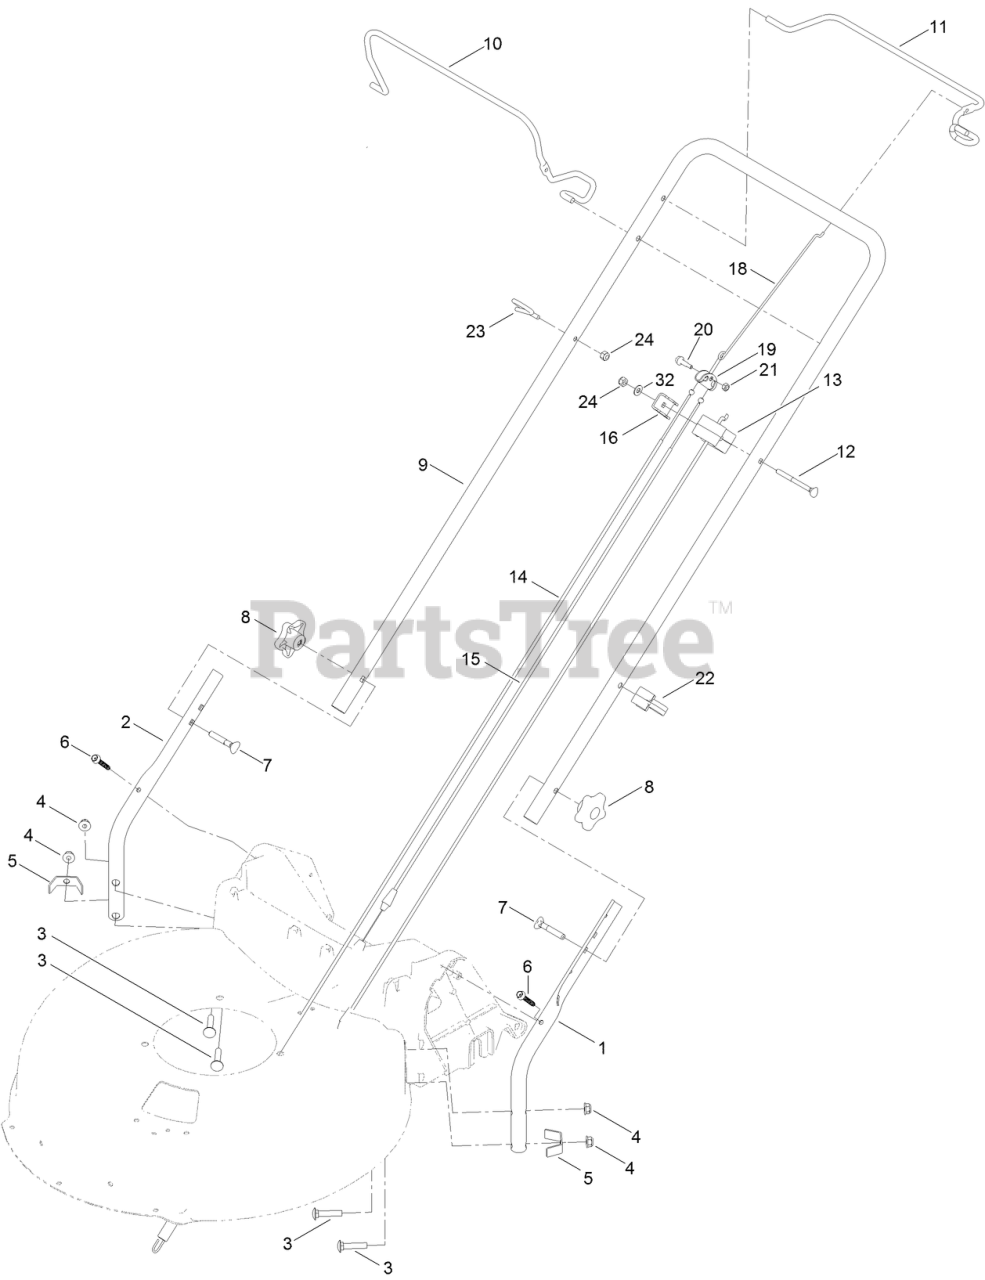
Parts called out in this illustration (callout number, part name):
1	HANDLE-LOWER, LH
2	HANDLE-LOWER, RH
3	BOLT-CARR
4	NUT-FLANGE, NI
5	BRACKET-CHUTE
6	SCREW-FLANGE, SERRATED
7	SCREW-HANDLE
8	KNOB-HANDLE
9	HANDLE-UPPER
11	BAIL-TRACTION
12	SCREW-HANDLE
13	CABLE-BRAKE
14	CABLE-TRACTION, FRONT
15	CABLE-TRACTION, REAR
16	CLAMP-CABLE
18	LINKAGE, EQUALIZER
19	YOKE-CABLE
20	SCREW-SHOULDER
21	NUT-LOCK, NI
22	GUIDE-CABLE
23	GUIDE-ROPE
24	NUT-LOCK, NI
32	WASHER-FLAT
